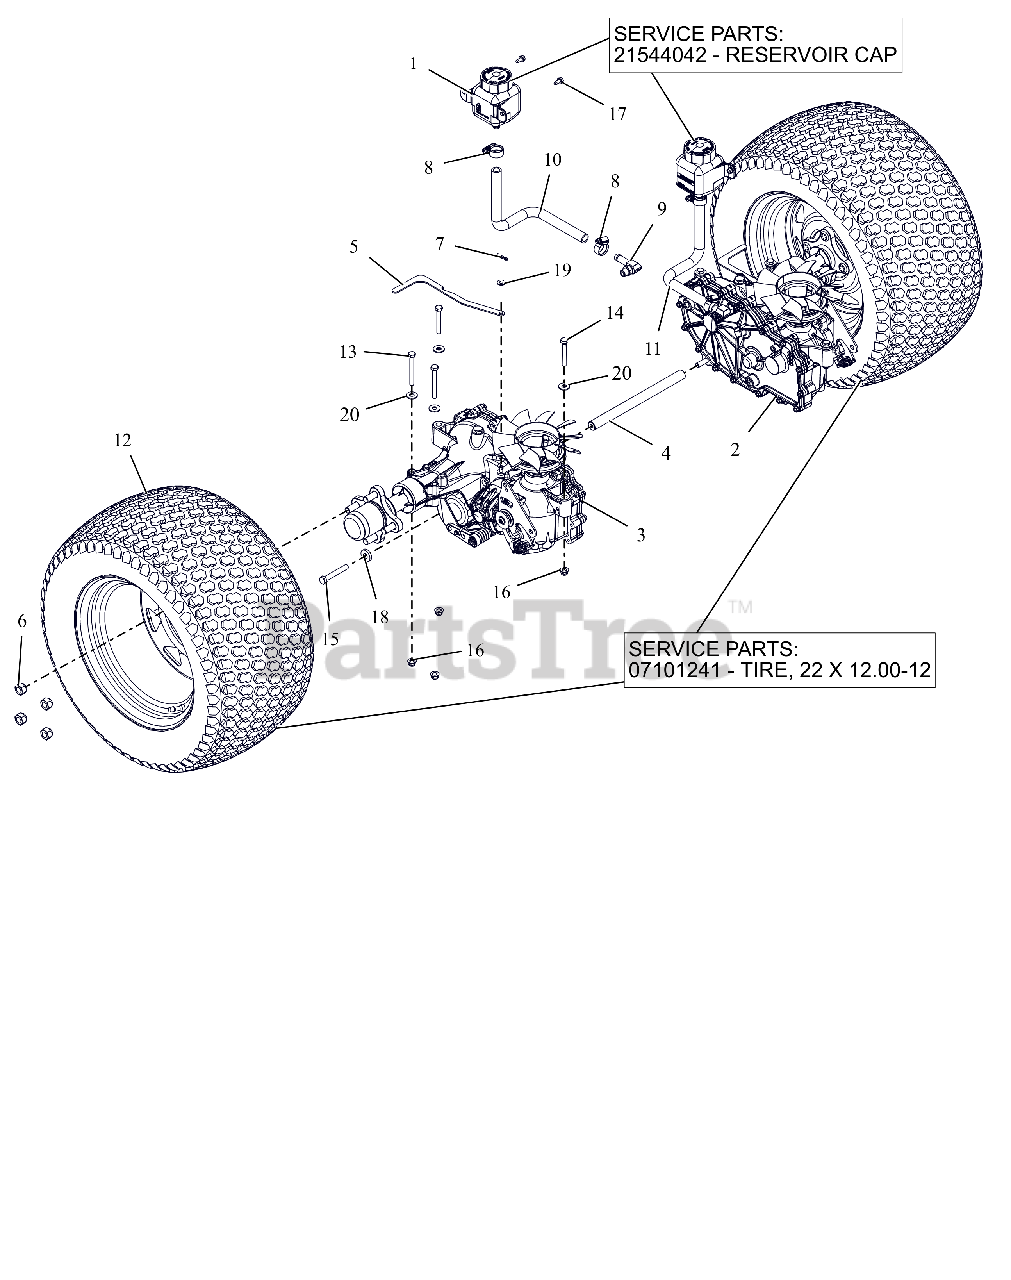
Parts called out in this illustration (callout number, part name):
1	TANK, EXPANSION
1	CAP, HYDRO RESERVOIR REPLAC.
2	TRANSAXLE, ZT3100 LH
3	TRANSAXLE, ZT3100 RH
4	SHAFT, TRANSAXLE SUPPORT
5	BRKT, VALVE DUMP
6	WHEEL NUT .500-20 YZ
7	PIN-HAIR, ENDRIES #25 YWZC
8	CLAMP,.88 DIA. HOSE
9	FITTING, HYD (90 DEG)
10	HOSE, FORMED EXPANSION -HD RH
11	HOSE, FORMED EXPANSION -HD LH
12	ASM, WHL/TIRE 22X12.00-12 K500
12	TIRE, 22X12.00-12
13	@BLT-HEX .31-18X2.75 GR5 YWZC
14	@BLT-HEX .31-18X2.25 GR5 YWZC
15	@BLT-HEX .38-16X2.50 GR5 YWZC
16	@NUT-LK-NYL-FLG .31-18 YWZC
17	SCR-TAP .25-20X.50 HWH TR YWZ
18	WSHR-FL-STL .406X1.00X.188 YWZ
19	@WSHR-FL-STL.281X.62X.065 YWZC
20	@WSHR-FL-STL.38X.875X.083 YWZC
